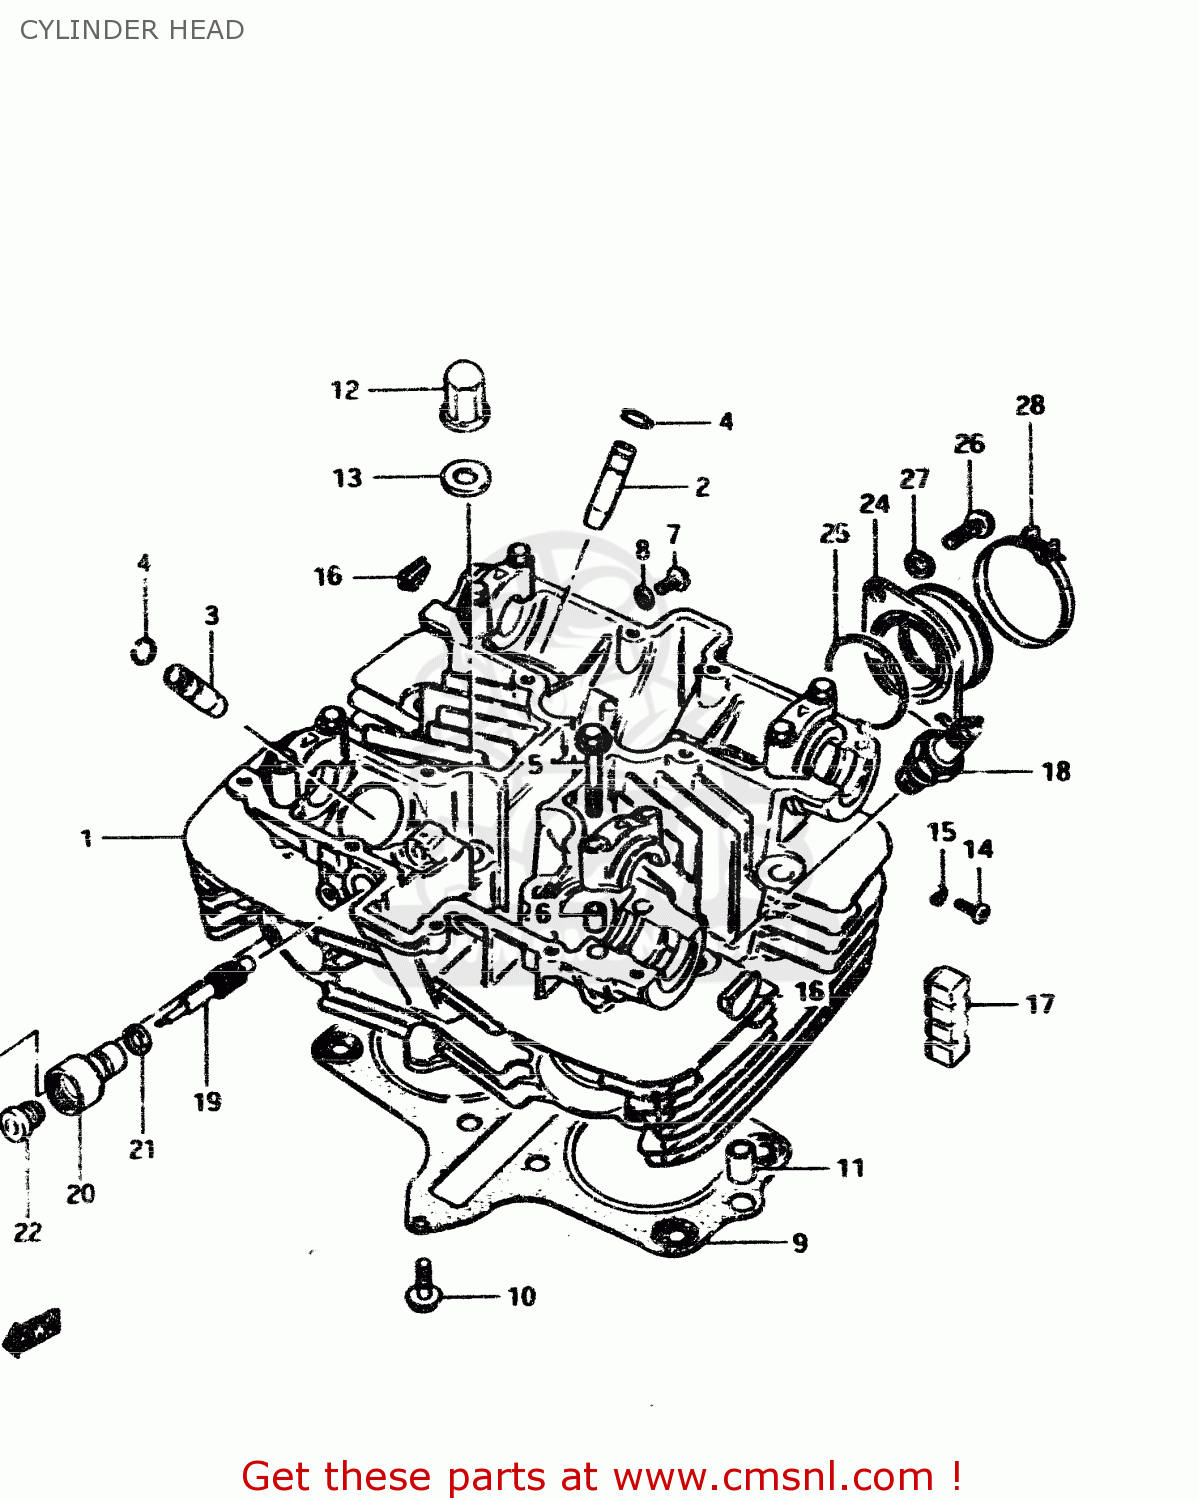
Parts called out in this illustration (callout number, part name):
1	HEAD SET,CYLINDER
2	GUIDE,INTAKE VALVE
3	GUIDE,EXHAUST VALVE
4	RING,SNAP
5	BOLT(6X39)
6	PIN(6.2X8X11)
7	BOLT
8	GASKET (NAS)
9	GASKET,CYLINDER HEAD (MCA)
10	BOLT 6X30
11	PIN
12	NUT
13	GASKET(10.5X22X2) (NAS)
14	SCREW
15	GASKET(5.3X9.3X1.2) (NAS)
16	PLUG
17	PAD,CYLINDER
18	SPARK PLUG W24ES-U
19	GEAR,TACHOMETER DRIVEN
20	SLEEVE,TACHOMETER DRIVE GEAR
21	SEAL,TACHOMETER DRIVEN
22	SEAL,OIL(5X12X8)
23	SCREW(5X12)
24	PIPE,INTAKE
25	O-RING (D:2.4 ID:39.7)
26	SCREW
27	LOCK WASHER
28	CLAMP
